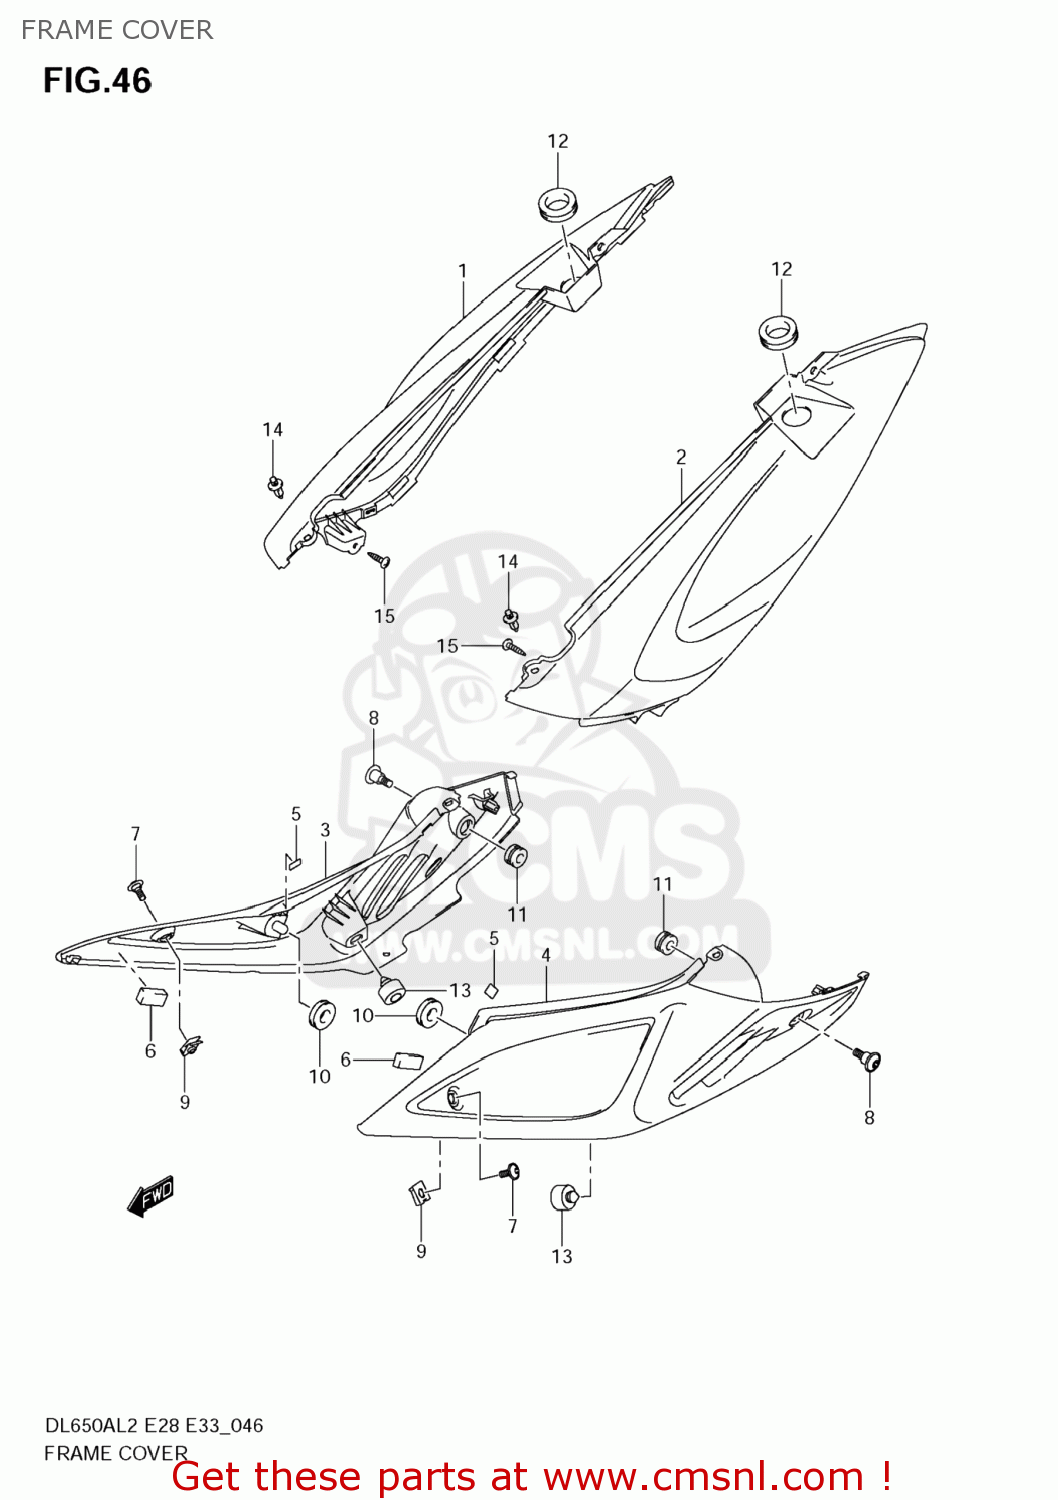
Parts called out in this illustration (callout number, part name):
1	COVER,FRAME,R(WHITE)
2	COVER,FRAME,L(WHITE)
3	COVER,FRAME SIDE,R
4	COVER,FRAME SIDE,L
5	CUSHION,RR COVER NO.2
6	CUSHION
7	BOLT(5X13)
8	BOLT(6X20)
9	NUT
10	CUSHION
11	CUSHION
12	CUSHION
13	CUSHION
14	CLIP(BLACK)
15	SCREW
